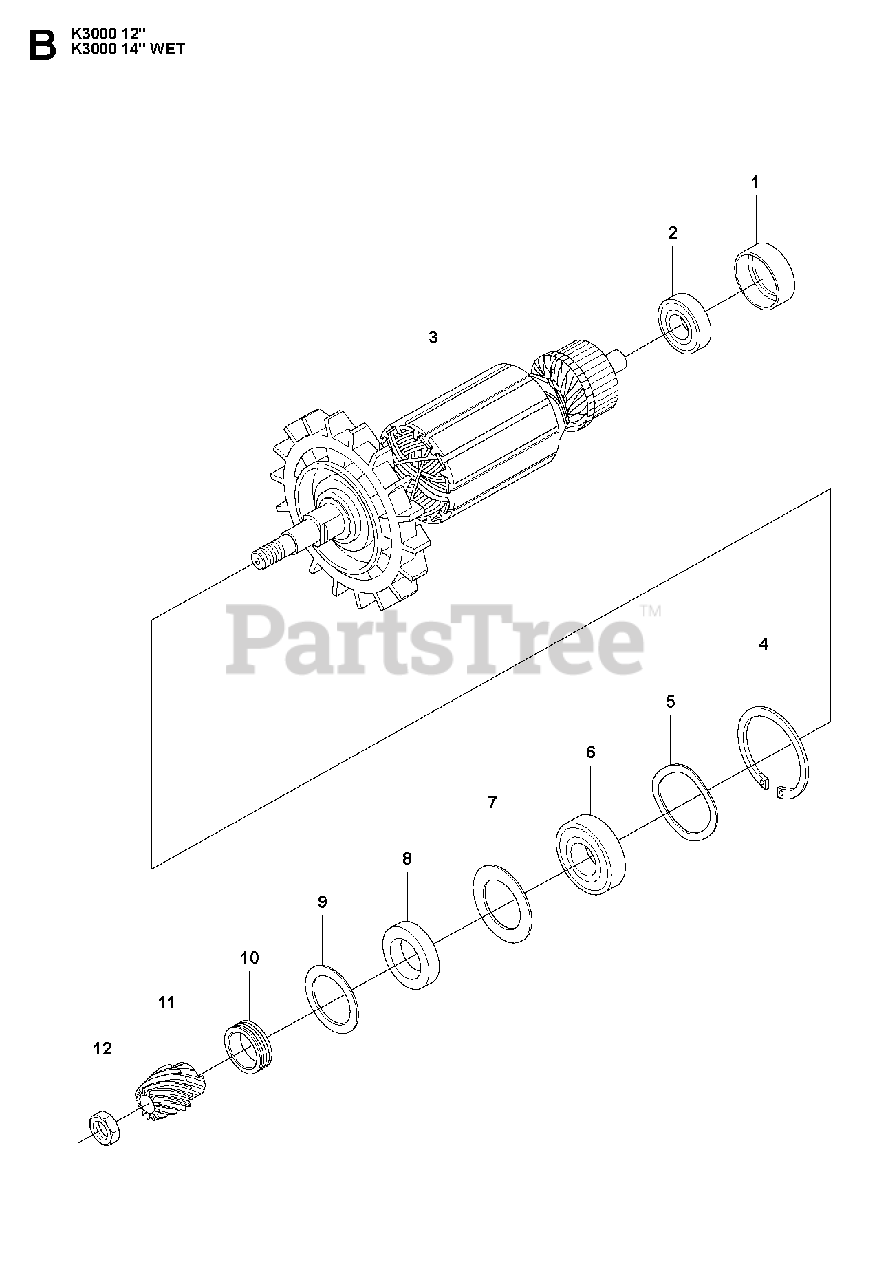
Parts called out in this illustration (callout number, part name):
1	RUBBER BUSHING
3	ARMATURE100 - 120V
3	ARMATURE230V
5	SPRING WASHER
6	BALL BEARING
12	HEXAGON NUT
